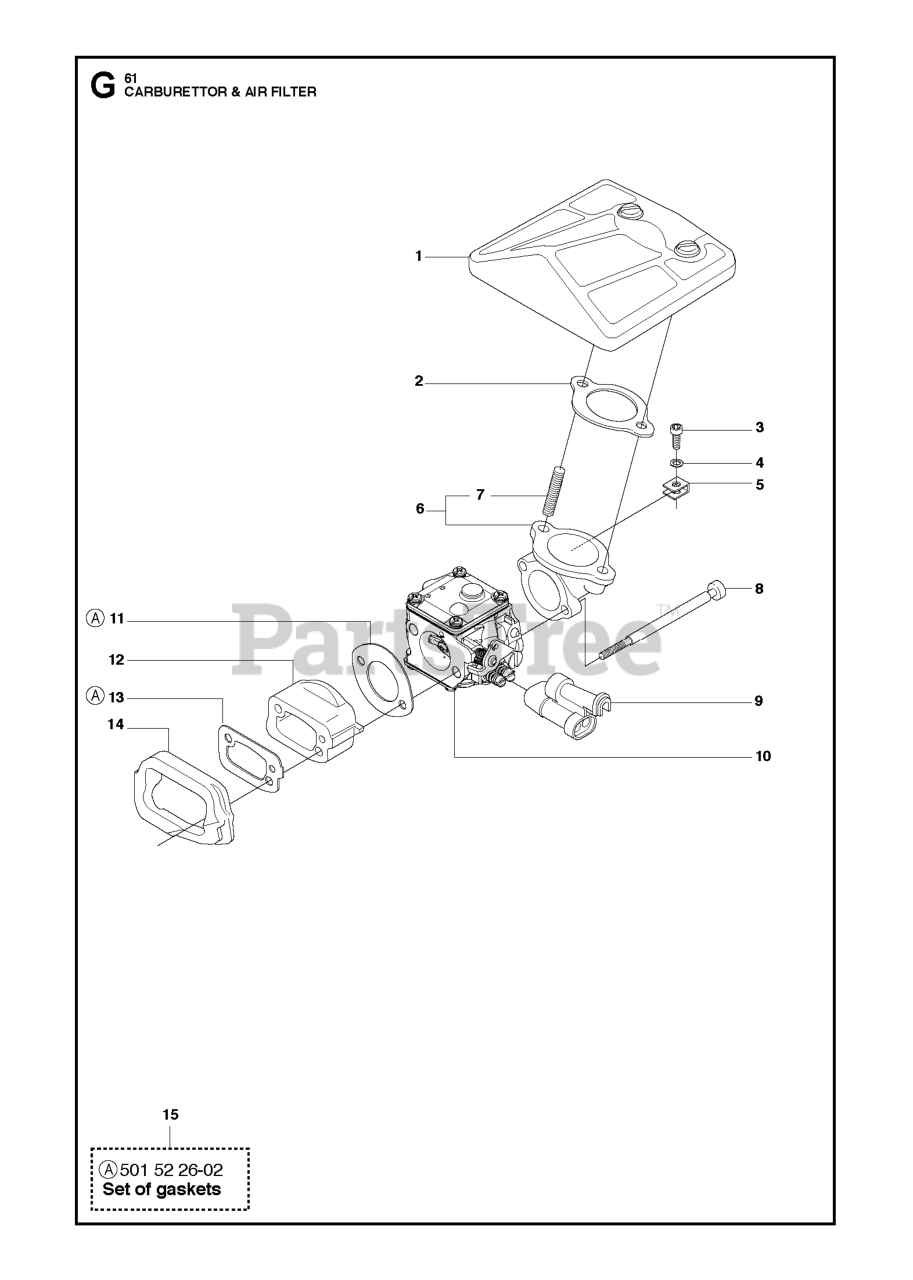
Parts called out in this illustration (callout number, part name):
1	AIR FILTER
1	AIR FILTER - FELT
3	SCREW MC6S 4X16
4	WASHER 4.2X9
6	AIR FILTER HOLDER
10	CARBURETOR
15	GASKET SET NLA
